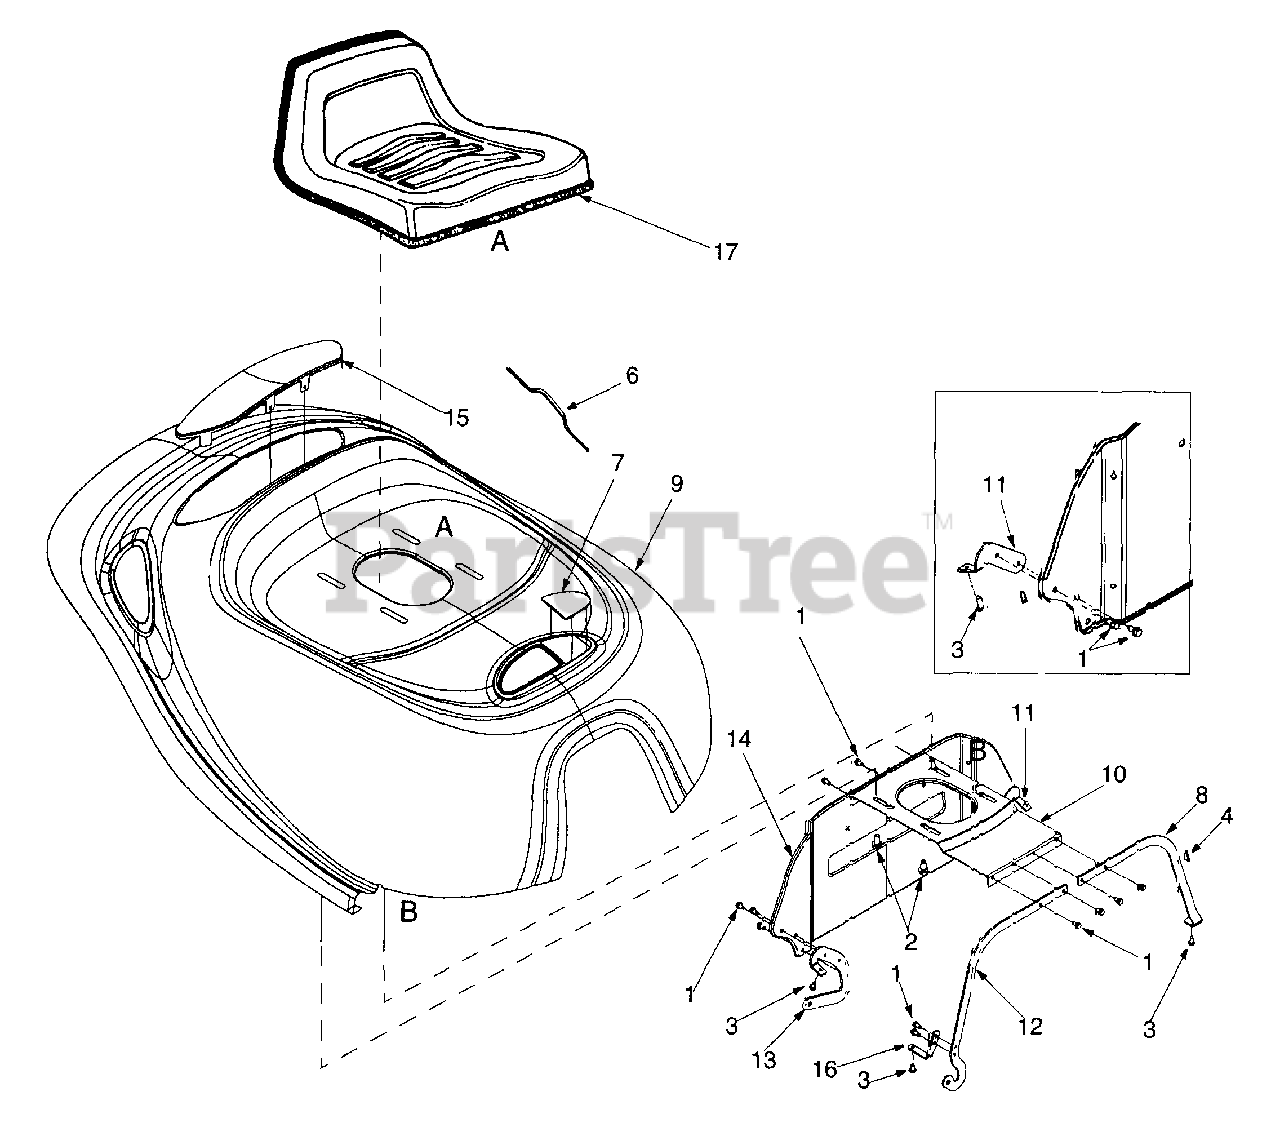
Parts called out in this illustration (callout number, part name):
1	Hex Hd. TT Screw 1/4-20 x 0.5
2	Hex Washer Hd. TT Screw 3/8-16 x 0.62
3	Torx Head AB screw 1/4-14 x 0.625
4	Rod End Grip
7	Grass Bag Lens
